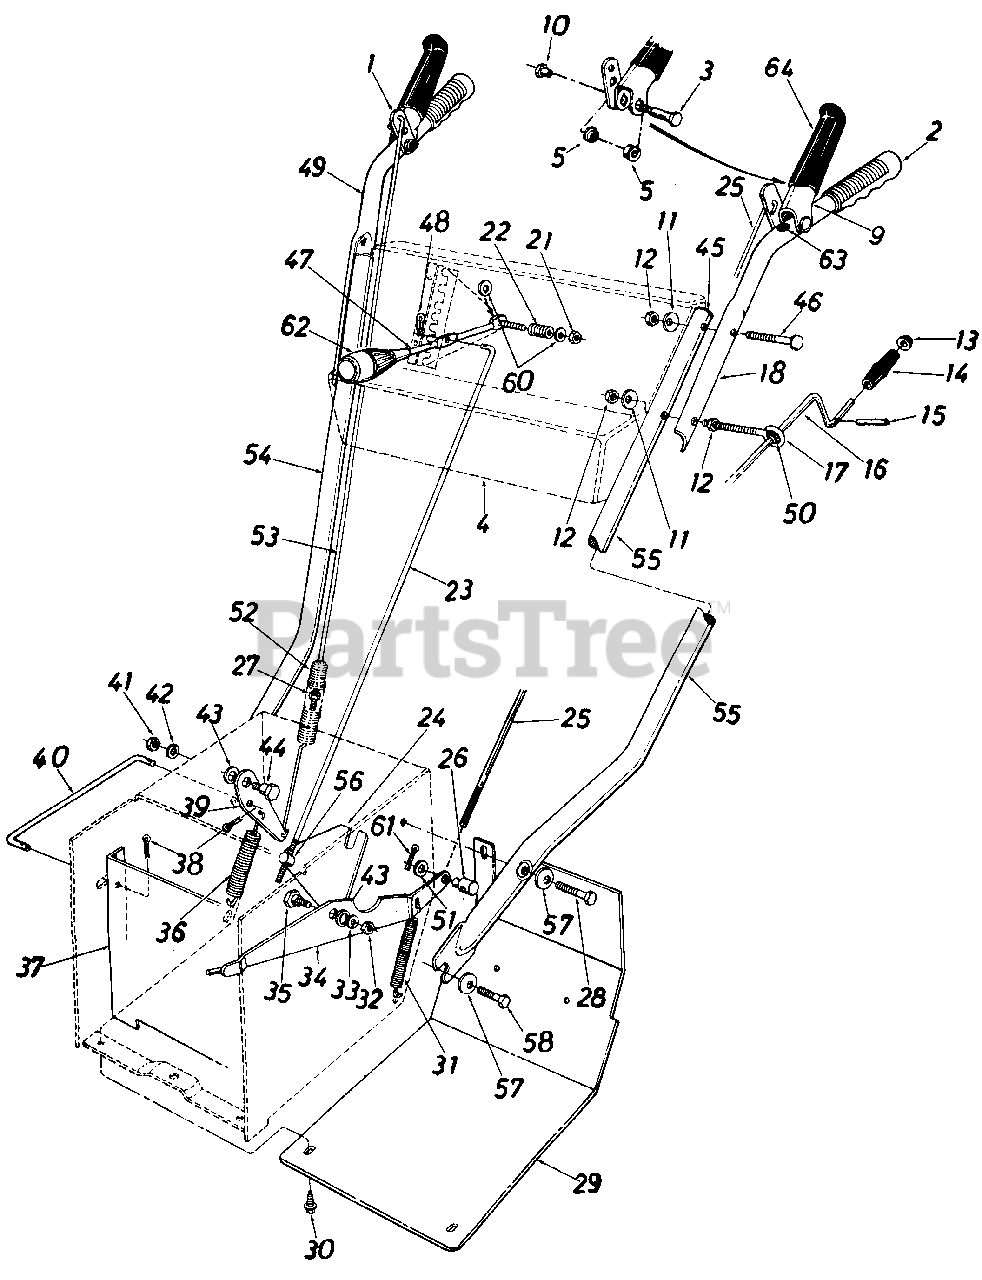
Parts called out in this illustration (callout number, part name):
1	Clutch Grip Ass'y. R.H.
2	Grip Red
3	Shoulder Bolt .374 Dia. x 1 .375" Lg.
4	Handle Panel Ass'y.
5	Hex Flange Plastic Bearing .380" I.D.
9	Clutch Grip Ass'y. L.H.
10	Shoulder Nut 1/4-20 Thd.
11	Bell-Wash. .34" I.D. x .88" O.D.
12	Hex Nut 5/16-18 Thd.
13	Push Nut 3/8" Rod
14	Knob 3/8" Rod
15	Roll Pin .12 Dia. x .63" Lg.
16	Chute Crank Ass'y. 39" Lg.
17	Eye Bolt 5/16-18 x 5.0" Lg.
18	Upper Handle L.H. (Painted)
21	Hex Ins. Jam L-Nut 5/16-18 Thd.
22	Compression Spring .50" O.D. x .88" Lg.
23	Shifting Rod 5/16" x 32.50n Lg.
24	Shifting Linkage Bracket
25	Lockout Rod .214" Dia. x 36.0" Lg.
26	Adjustment Ferrule 1/4-20
27	Hex Ins. L-Nut 1/4-20 Thd.
28	Hex Bolt 3/8-16 x 2.00" Lg.
29	Frame Cover
30	Hex Wash. Self-Tap Scr. 1/4-20 x .50" Lg.
31	Extension Spring .38" O.D. x 3.25" Lg.
32	Hex Jam Nut 3/8-16 Thd.
33	L-Wash. 3/8" I.D.
34	Auger Clutch Bracket Ass'y.
35	Shld. Bolt .625'1 Dia. x .170
36	Extension Spring .75" O.D. x 4.31 " Lg.
37	Drive Pulley Support Brkt. Ass'y.
38	Cotter Pin 3/32" Dia. x .75" Lg.
39	Drive Clutch Bracket
40	Drive Clutch Rod
41	Hex Jam Nut 3/8-16 Thd.
42	L-Wash. 3/8" I.D.
43	Bell-Wash. .40" I.D. x 1.13" O.D.
44	Shld. Bolt .625" Dia. x .170
45	Plastic Plug
46	Carriage Bolt 5/16-18 x 2.0" Lg.
47	Shift Handle
48	Int. Cotter Pin 5/16" Dia.
50	Plastic Bushing
51	Fl-Wash. .344" I.D. x .62" O.D.
52	Extension Spring 75" O.D. x 5.00" Lg.
53	Lockout Rod .214" Dia. x 32" Lg.
54	Lower Handle R.H. (Painted)
55	Lower Handle L.H. (Painted)
56	Adjustment Ferrule
57	Bell-Wash. .40" I.D. x .88" O.D.
58	Hex Wash. Self-Tap Scr. 3/8-16 x .75" Lg.
60	Fl-Wash. .344" I.D. x .62" O.D.
61	Cotter Pin 3/32" Dia.
63	Push Cap
64	Black Vinyl Grip
